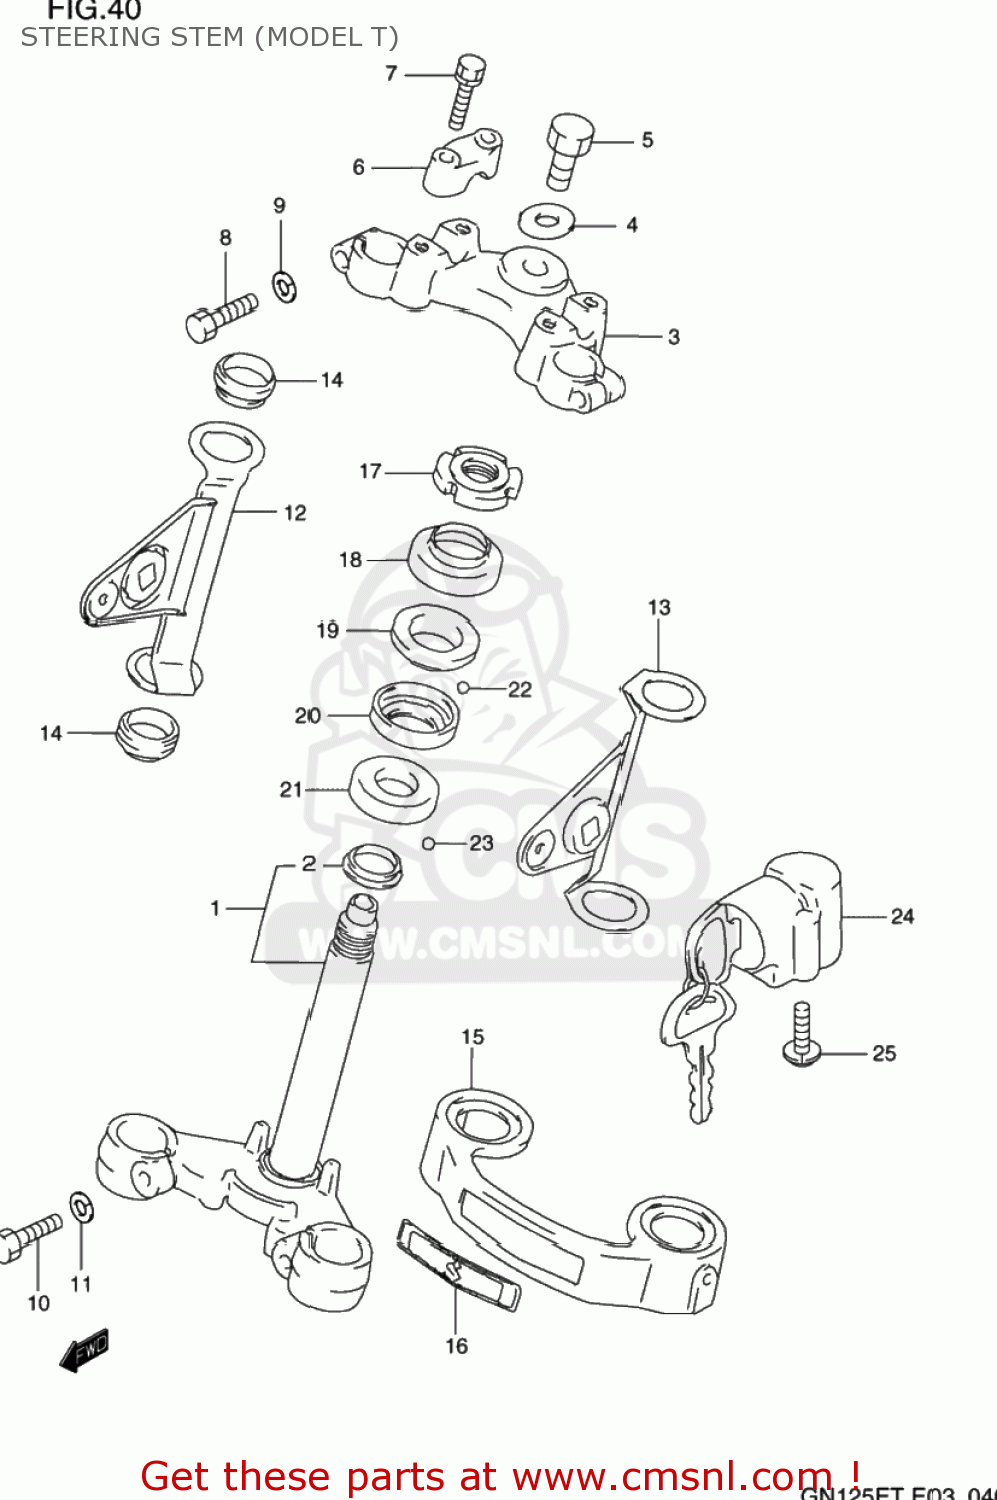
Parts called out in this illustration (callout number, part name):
1	STEM,STEERING
2	RACE,STEERING OUTER LWR
3	HEAD,STEERING STEM(BLACK)
4	WASHER,STEM HEAD(10.5X30X3.2)
5	BOLT,FR FORK(10X33)
6	HOLDER,HANDLE(BLACK)
7	BOLT
8	BOLT
9	WASHER,LOCK
10	BOLT,FR FORK LWR(12X33)
11	WASHER,LOCK
12	BRACKET,HEADLAMP,R
13	BRACKET,HEADLAMP,L
14	CUSHION,HEADLAMP BRACKET
15	COVER,FR FORK
16	EMBLEM,FR FORK COVER
17	NUT,STEERING STEM(25X44X10)
18	DUST SEAL,STEERING UPR
19	RACE,STEERING OUTER UPR
20	RACE,STEERING INNER UPR
21	LACE,STEERING INNER LWR
22	BALL
23	BALL
24	LOCK ASSY,STEERING
25	SCREW
